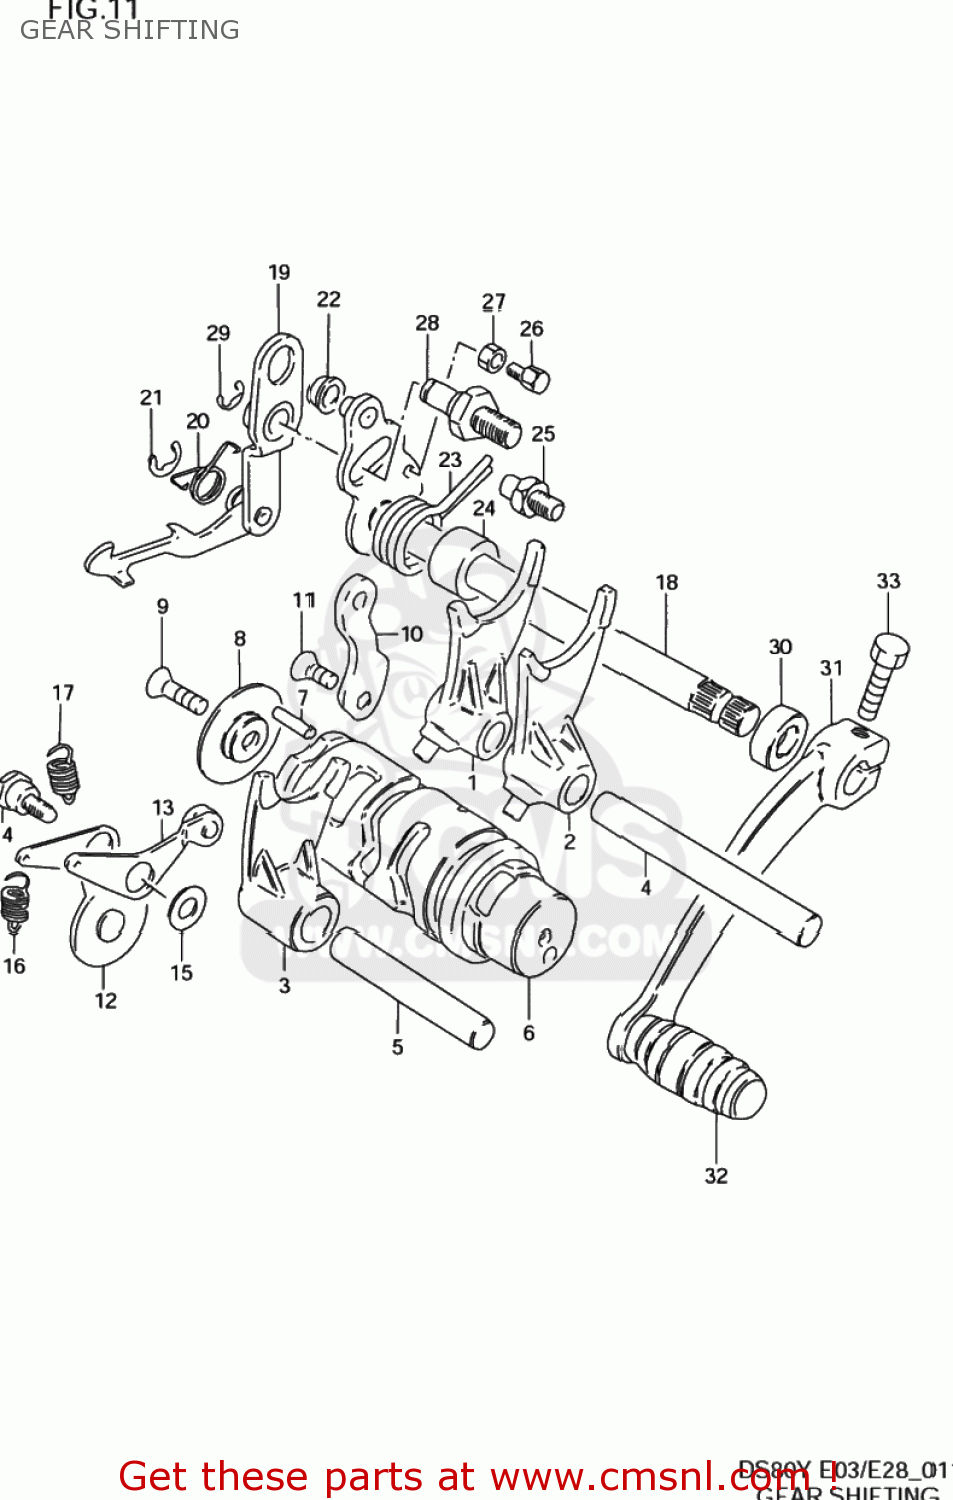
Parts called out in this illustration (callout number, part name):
1	FORK,GEAR SHIFT NO.1
2	FORK,GEAR SHIFT NO.2
3	FORK,GEAR SHIFT NO.2
4	SHAFT,GEAR SHIFT FORK
5	SHAFT,GEAR SHIFT FORK
6	CAM,GEAR SHIFT
7	PIN
8	RETAINER,GEAR SHIFT CAM DR PIN
9	SCREW
10	GUIDE,GEAR SHIFT CAM
11	SCREW
12	STOPPER,GEAR SHIFT CAM
13	STOPPER,GEAR SHIFT CAM NEUTRAL
14	BOLT(6X18.3)
15	WASHER
16	SPRING
17	SPRING
18	SHAFT,GEAR SHIFT
19	PAWL,GEAR SHIFT
20	SPRING
21	E-RING
22	SPACER(7X10X5)
23	SPRING
24	SPACER(12X20X15.3)
25	STOPPER,GEAR SHIFT CAM
26	BOLT,GEAR SHAFT RETURN SPR SET
27	NUT
28	STOPPER,GEAR SHIFT CAM
29	E.RING
30	OIL SEAL
31	LEVER ASSY,GEAR SHIFT
32	RUBBER,GEAR SHIFT PEDAL
33	BOLT
